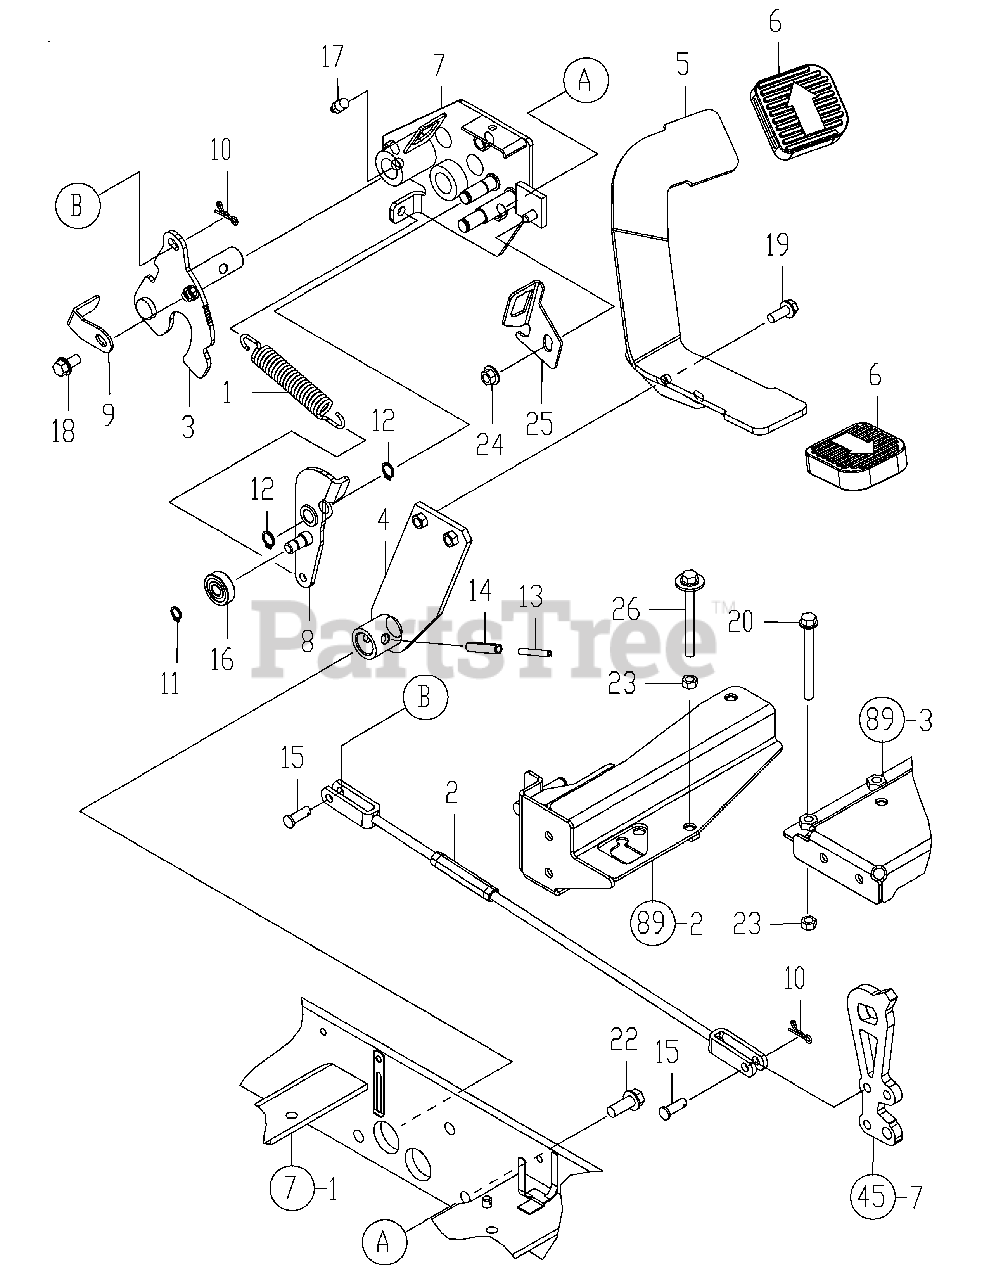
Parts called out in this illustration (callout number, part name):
1	SPRING, RETURN
5	PEDAL ,HST CMP
7	FULCRUM, PEDAL CMP
8	ARM, SWITCH CMP
13	PIN, 5.0A X 40
14	PIN, 8.0A X 40
16	BEARING, 6200UU
17	FITTING, PT 1/8
26	BOLT, HST PEDAL
